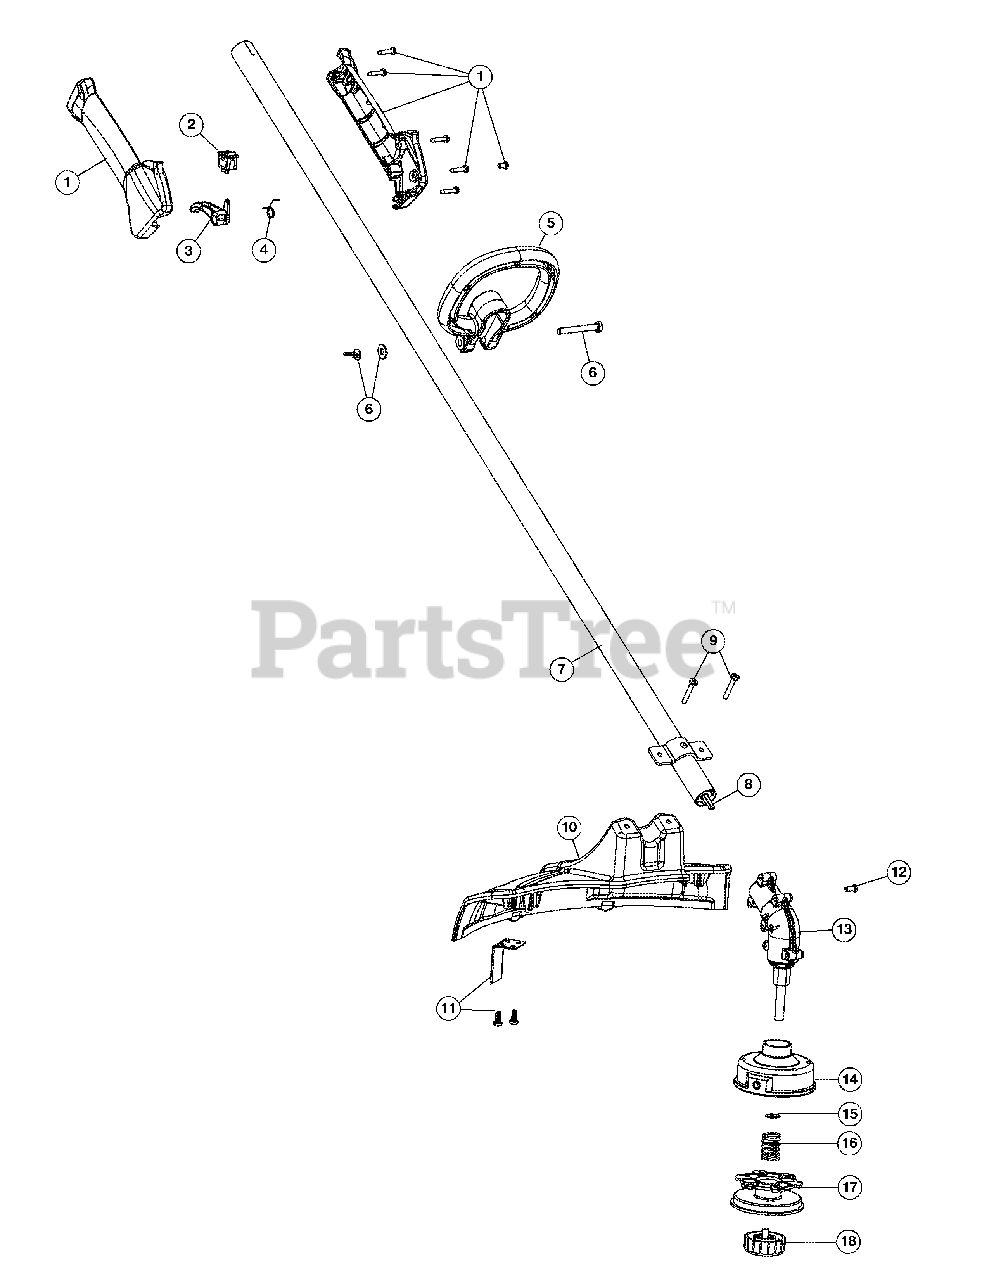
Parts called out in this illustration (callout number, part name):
1	Throttle Housing Assembly (Incl. Ref No. 2-4)
3	Throttle Trigger
4	Throttle Trigger Spring
5	D-Handle (Incl. Ref No. 6)
6	D-Handle Hardware Assembly
7	Drive Shaft Housing Assembly (Incl. Ref No. 8)
8	Flexible Drive Shaft
9	Shield Mounting Screw
10	Shield Assembly (Incl. Ref No. 9 & 11)
11	Blade Assembly
12	Anti-Rotation Screw
13	Gearbox Assembly (Incl. Ref No. 14-18)
14	Outer Spool Assembly (Incl. Ref No. 15)
15	Retainer
17	Inner Reel
18	Bump Head Knob Assembly
